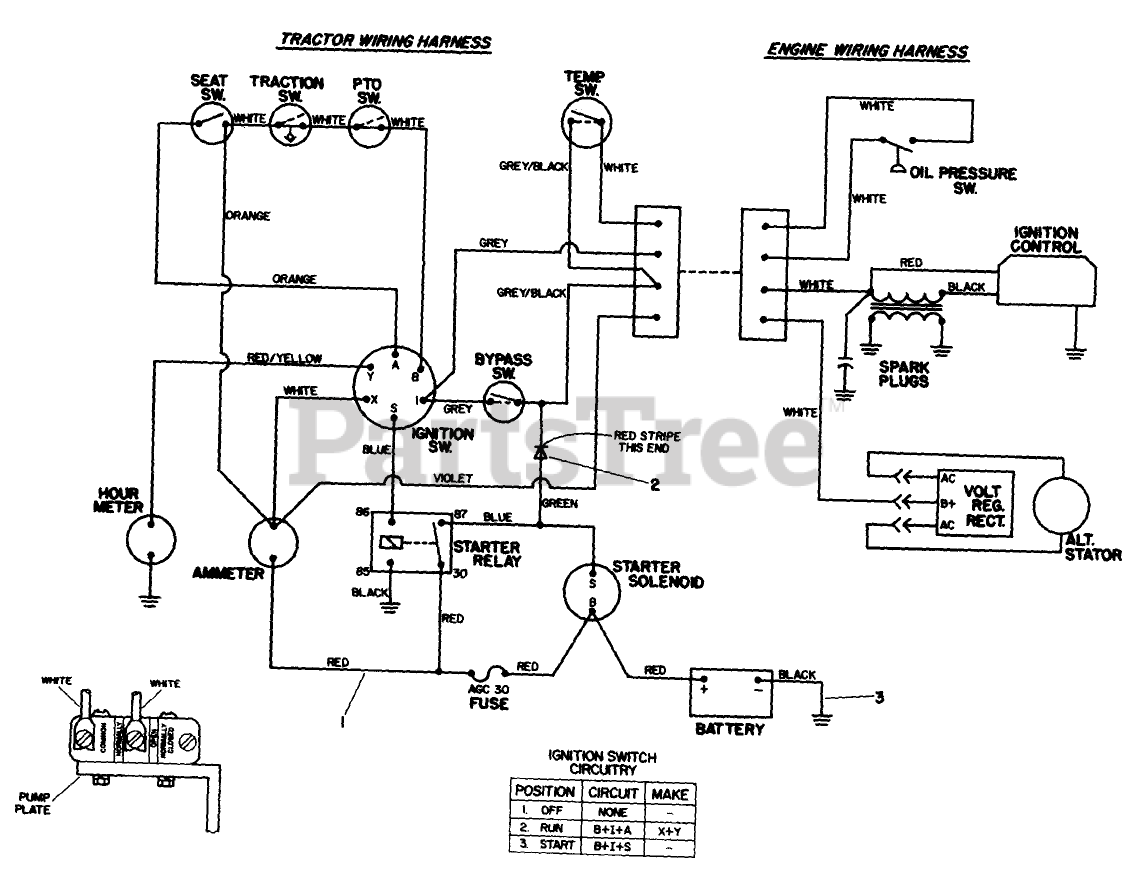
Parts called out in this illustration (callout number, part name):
1	Wire Harness (Incl. Ref. #2)
2	DIODE
3	BATTERY GROUND WIRE
